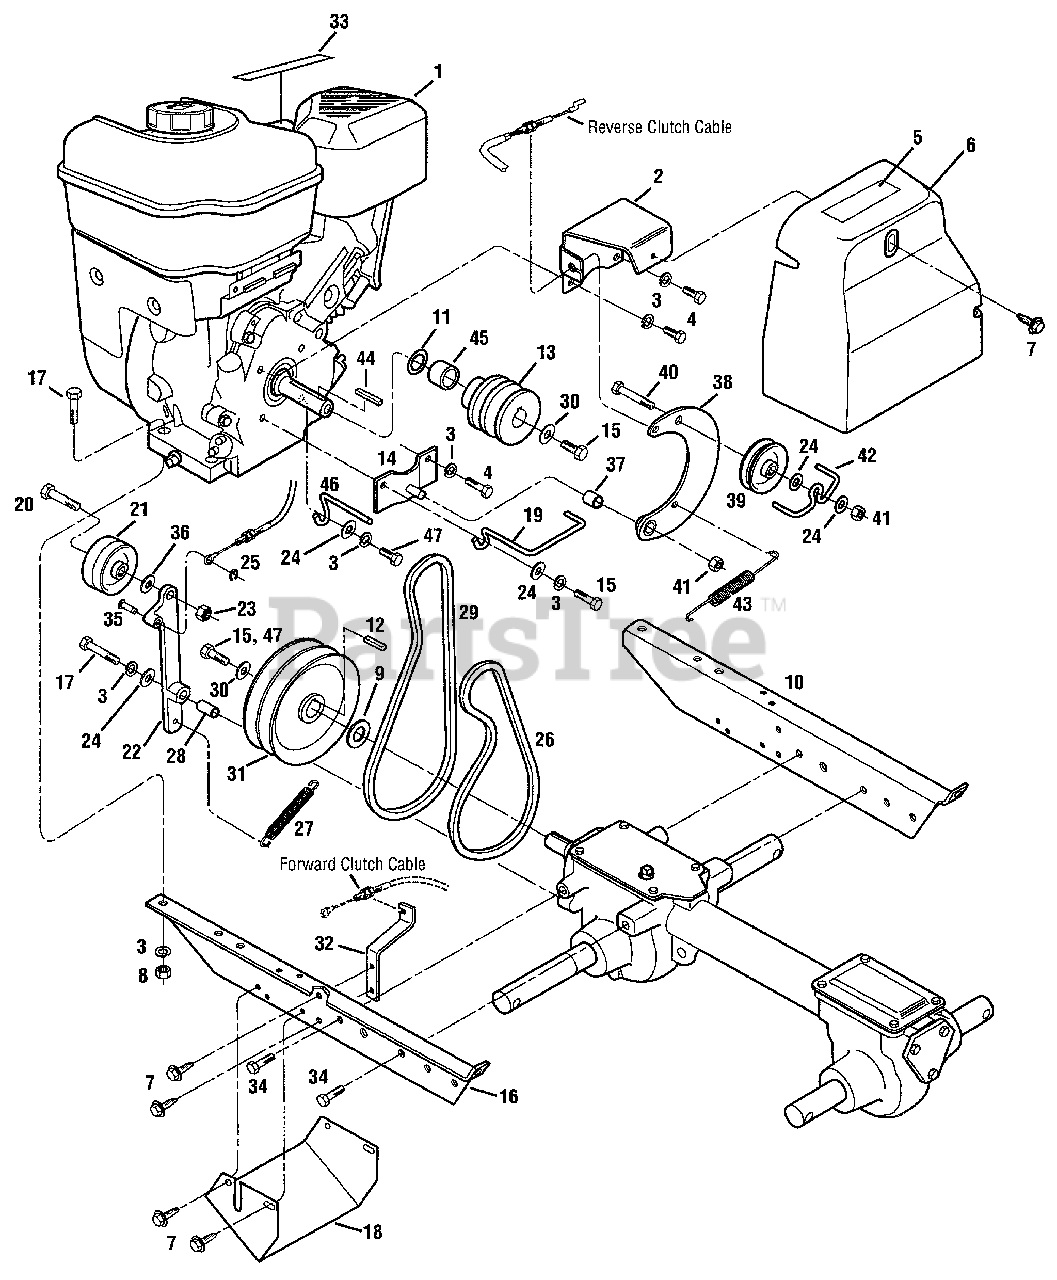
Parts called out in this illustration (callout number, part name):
1	Engine, Recoil Start
2	Bracket, Belt Cover
3	Lock Washer, 5/16
4	Hex Hd. Screw, 5/16-24 x 1/2
5	Decal, Hot Surfaces Warning
6	Belt Cover
7	Hex Hd. Flange Screw, Self-Tapping, 1/4-20 x 1/2
8	Hex Nut, 5/16-18
9	Support Washer
10	Engine Bracket, Right
11	Shim
12	Key, 3/16" x 1"
13	Pulley, Engine Drive
14	Reverse Idler Bracket
15	Hex Hd. Screw, 5/16-24 x 1
16	Engine Bracket, Left
17	Hex Hd. Screw, 5/16-18 x 1-1/2
18	Guard, Belts/Pulleys
19	Forward Belt Guide
20	Hex Hd. Screw, 3/8-16 x 1-1/2
21	Forward Idler Pulley
22	Forward Idler Lever
23	Lock Nut, 3/8-16
24	Flat Washer
25	Up Ring
26	Forward Drive Belt
27	Forward Return Spring
28	Bushing, Forward Idler Lever
29	Reverse Drive Belt MR
30	Belleville Washer
31	Transmission Pulley
32	Bracket, Cable Mounting
33	Decal, Stabilization
34	Hex Hd. Screw, 5/16-18 x 5/8
35	Clevis Pin
36	Flat Washer, 3/8
37	Bushing
38	Reverse Idler Arm
39	Pulley, Reverse Idler
40	Hex Hd. Screw, 5/16-18 x 2
41	Lock Nut, 5/16-18
42	Belt Guide
43	Reverse Return Spring
44	Key, 3/16" x 1-1/2"
45	Spacer
46	Forward Belt Guide
47	Hex Hd. Screw, 5/16-24 x 3/4
